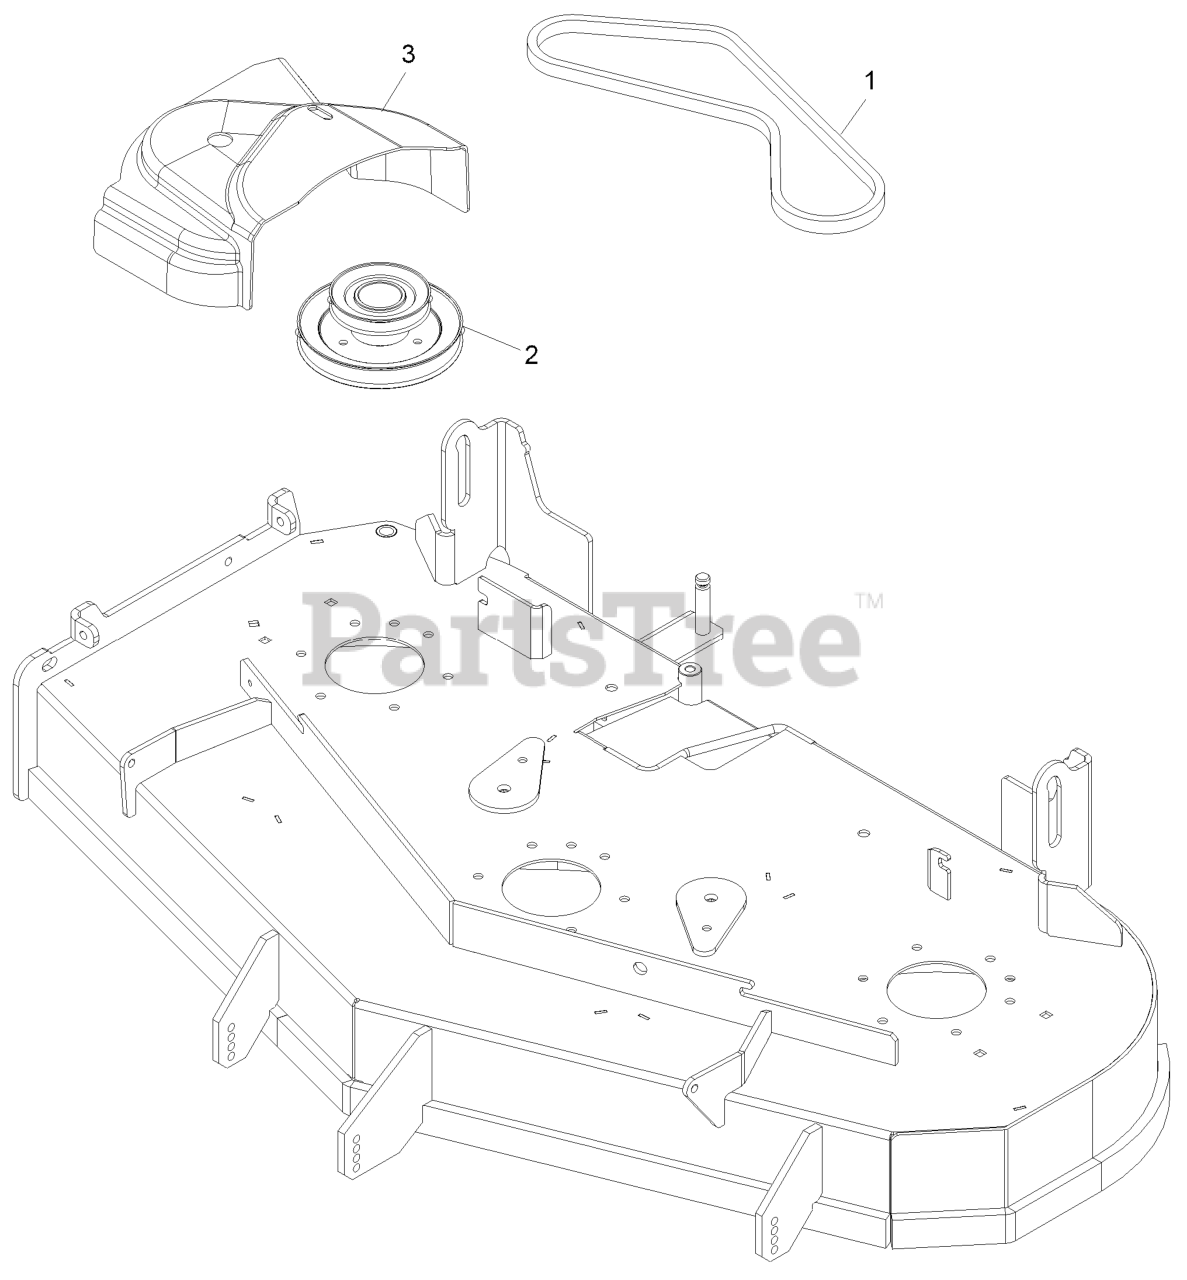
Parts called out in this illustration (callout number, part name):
1	BELT, BLOWER 52"DECK
2	JACKSHAFT,UV DRIVE 524 SP
3	COVER,BELT UV 52
